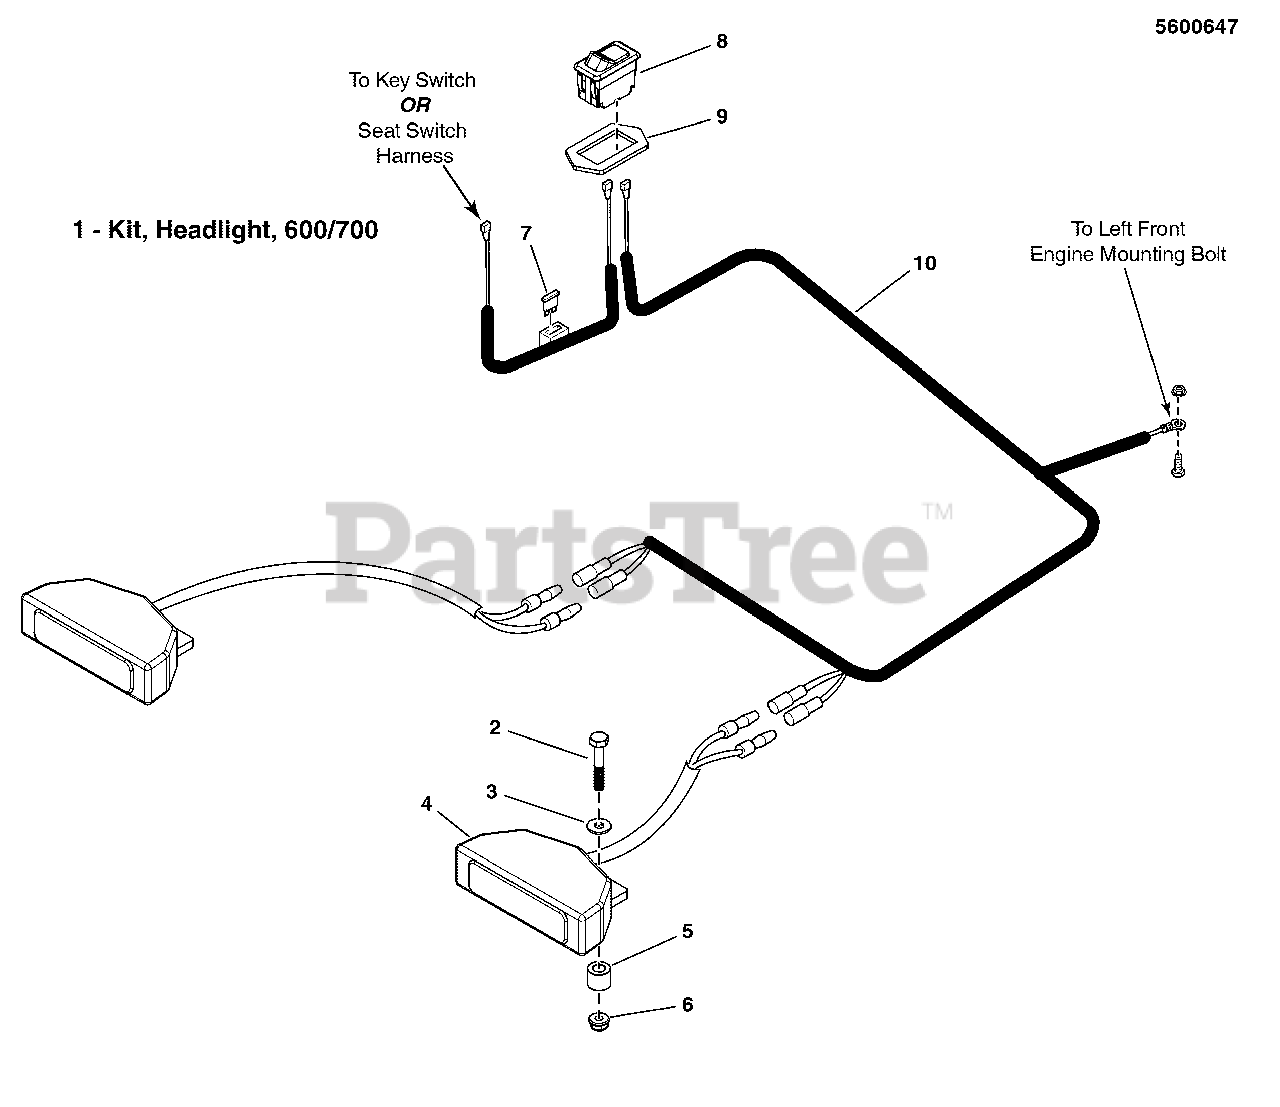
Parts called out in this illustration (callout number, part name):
1	Kit, Headlight, 600/700
2	BOLT, 1/4-20 X 1-1/2 GD5 CZ
3	WASHER, 1/4 SAE
4	HEADLIGHT-4 RECT.
4	HEADLIGHT, 5104888 W/ SHRINK TUBE
5	SPACER, .33 X .63 X .50, CZ
6	NUT, 1/4-20 Hex Nylock Flange
7	FUSE, ATO-15 (15 AMP)(SV)
8	SWITCH, HEADLIGHT
9	RING, SWITCH RETAINER
10	WIRE HARNESS, HEADLIGHT KIT, 600/700
